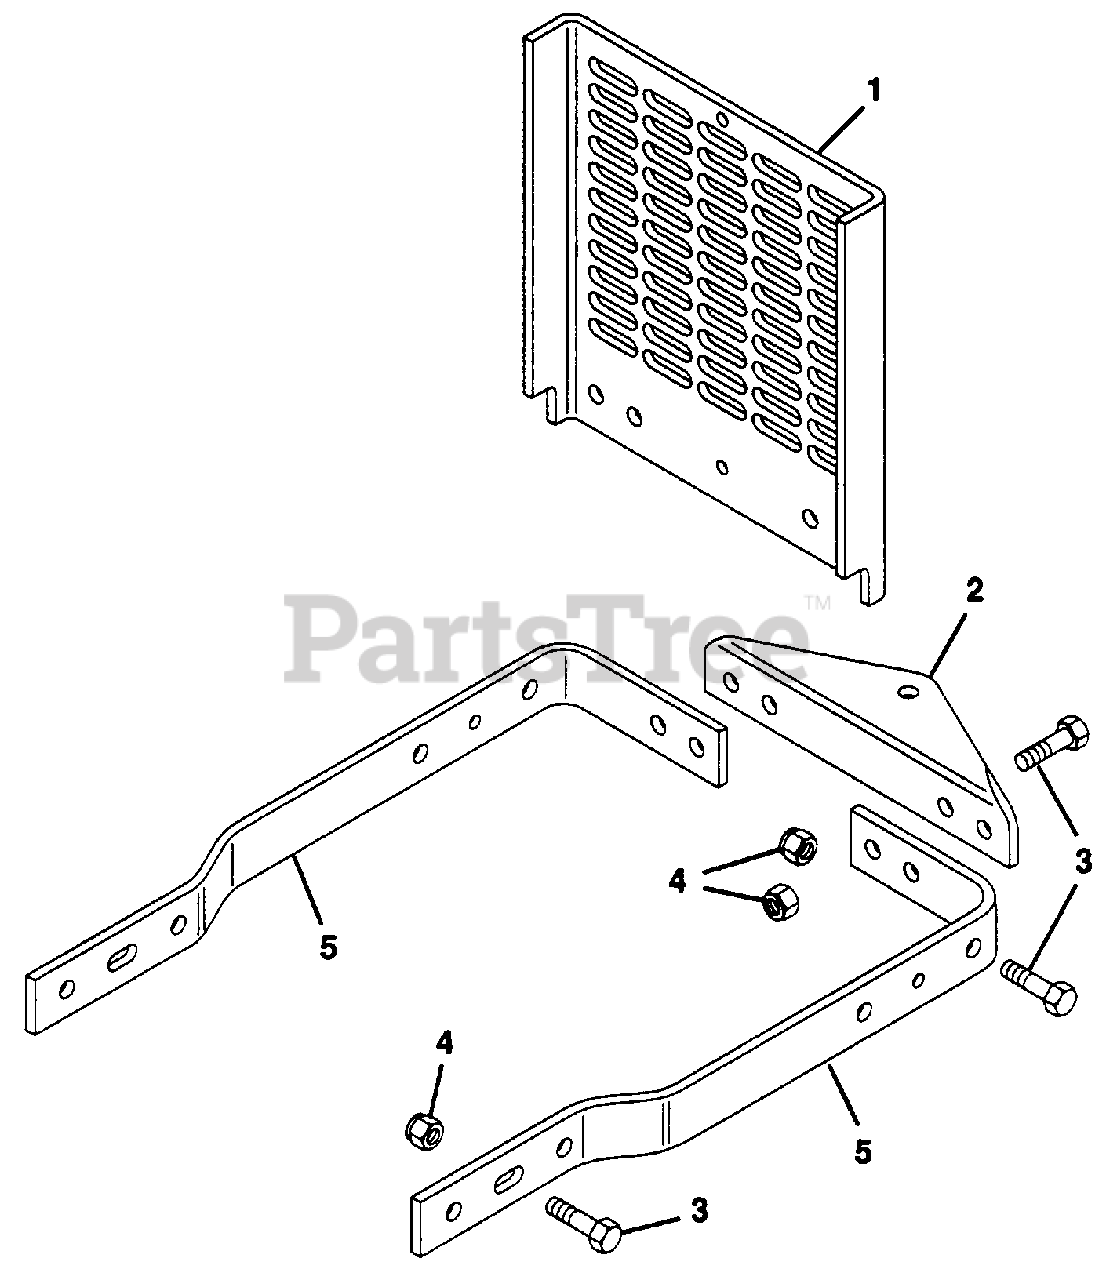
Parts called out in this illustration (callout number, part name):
1	GUARD, ENGINE
2	PLATE, HITCH
3	BOLT, HEX 1/2-13X1.75
4	NUT, LOCK 1/2-13
5	ARM, REAR HITCH
